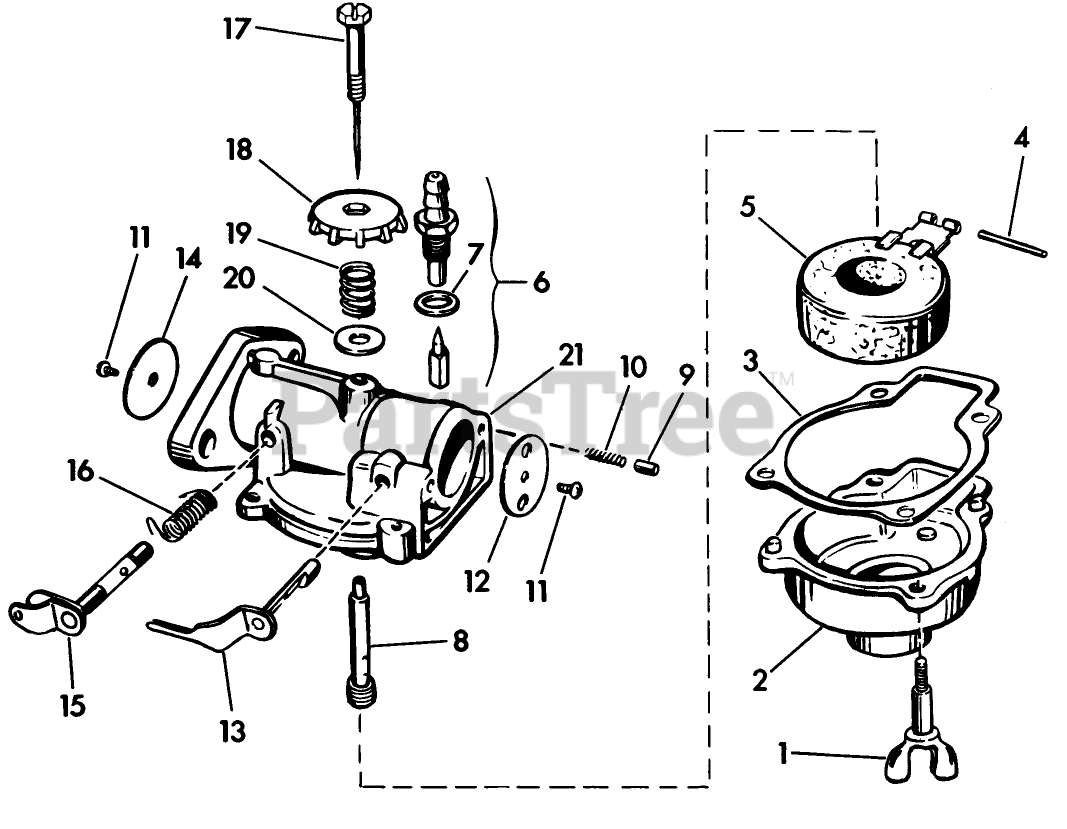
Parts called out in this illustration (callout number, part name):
11	Screw-Choke Disc
13	CHOKE SHAFT&LVR AY
17	NEEDLE AY. S
19	Spring-Ndl. Adj.
20	Washer-Needle Adjustment
